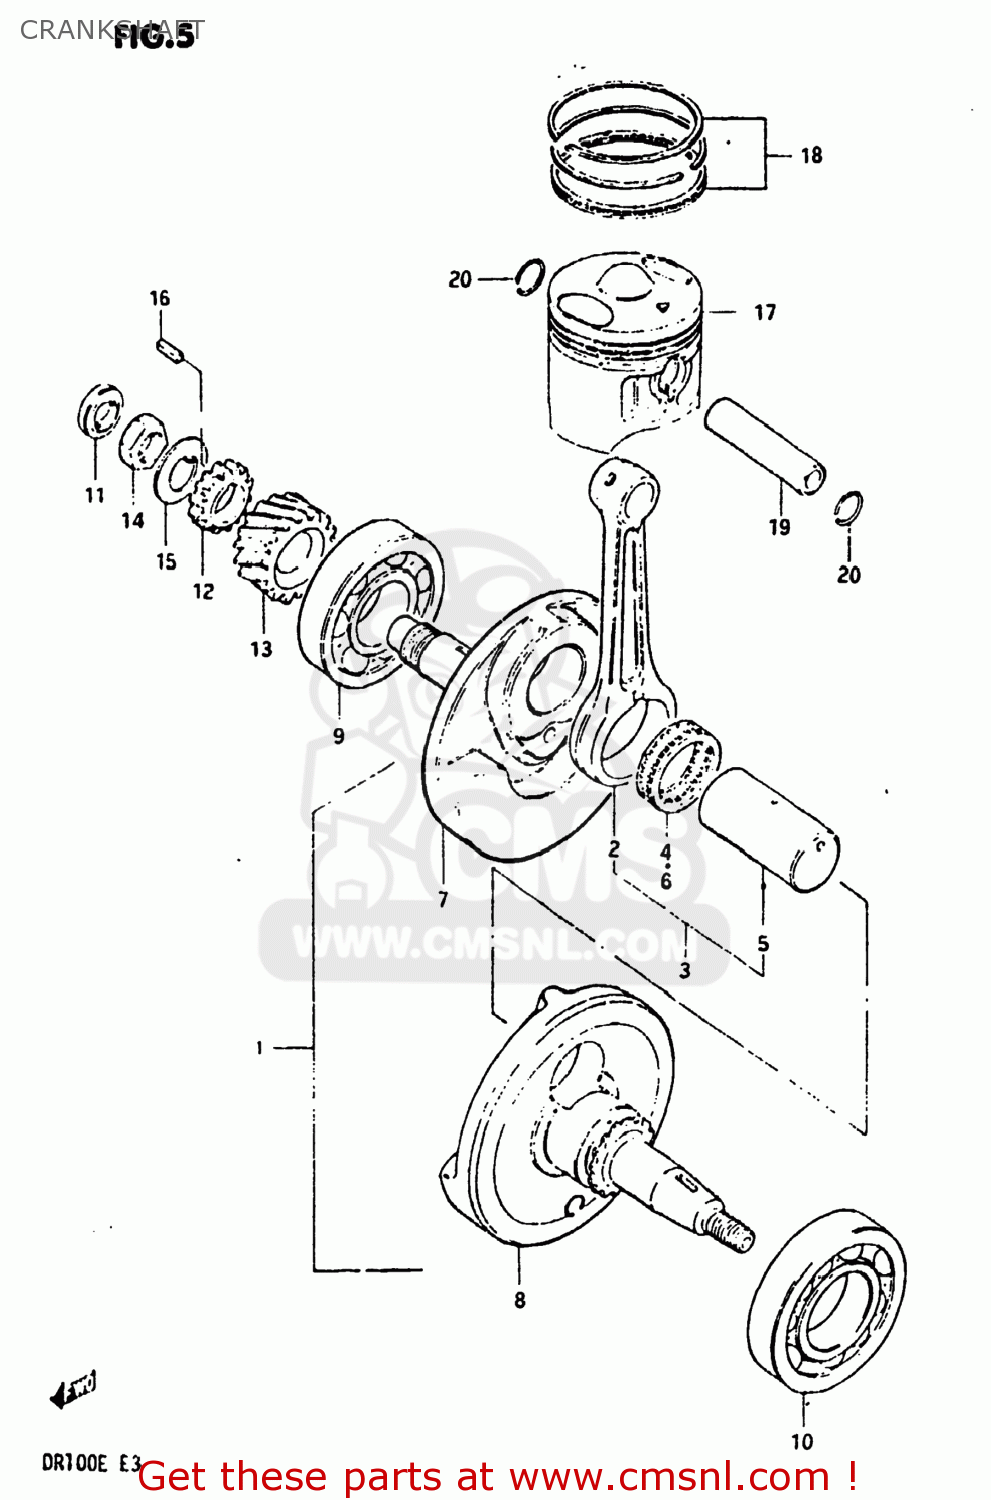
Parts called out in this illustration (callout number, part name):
1	CRANKSHAFT ASSEMBLY
2	CONNECTING ROD
3	CRANKSHAFT ASSEMBLY
4	BEARING
5	PIN,CRANK
6	BEARING
7	CRANKSHAFT,RIGHT
8	CRANKSHAFT,LEFT
9	BEARING,MIDDLE
10	BEARING,LEFT
11	OIL SEAL
12	GEAR,OIL PUMP DRIVE
13	GEAR,PRIMARY DRIVE
14	NUT
15	WASHER
16	KEY
17	PISTON (51.00MM)
18	RING SET,PISTON
19	RING,PISTON
20	RING,SNAP 14MM
